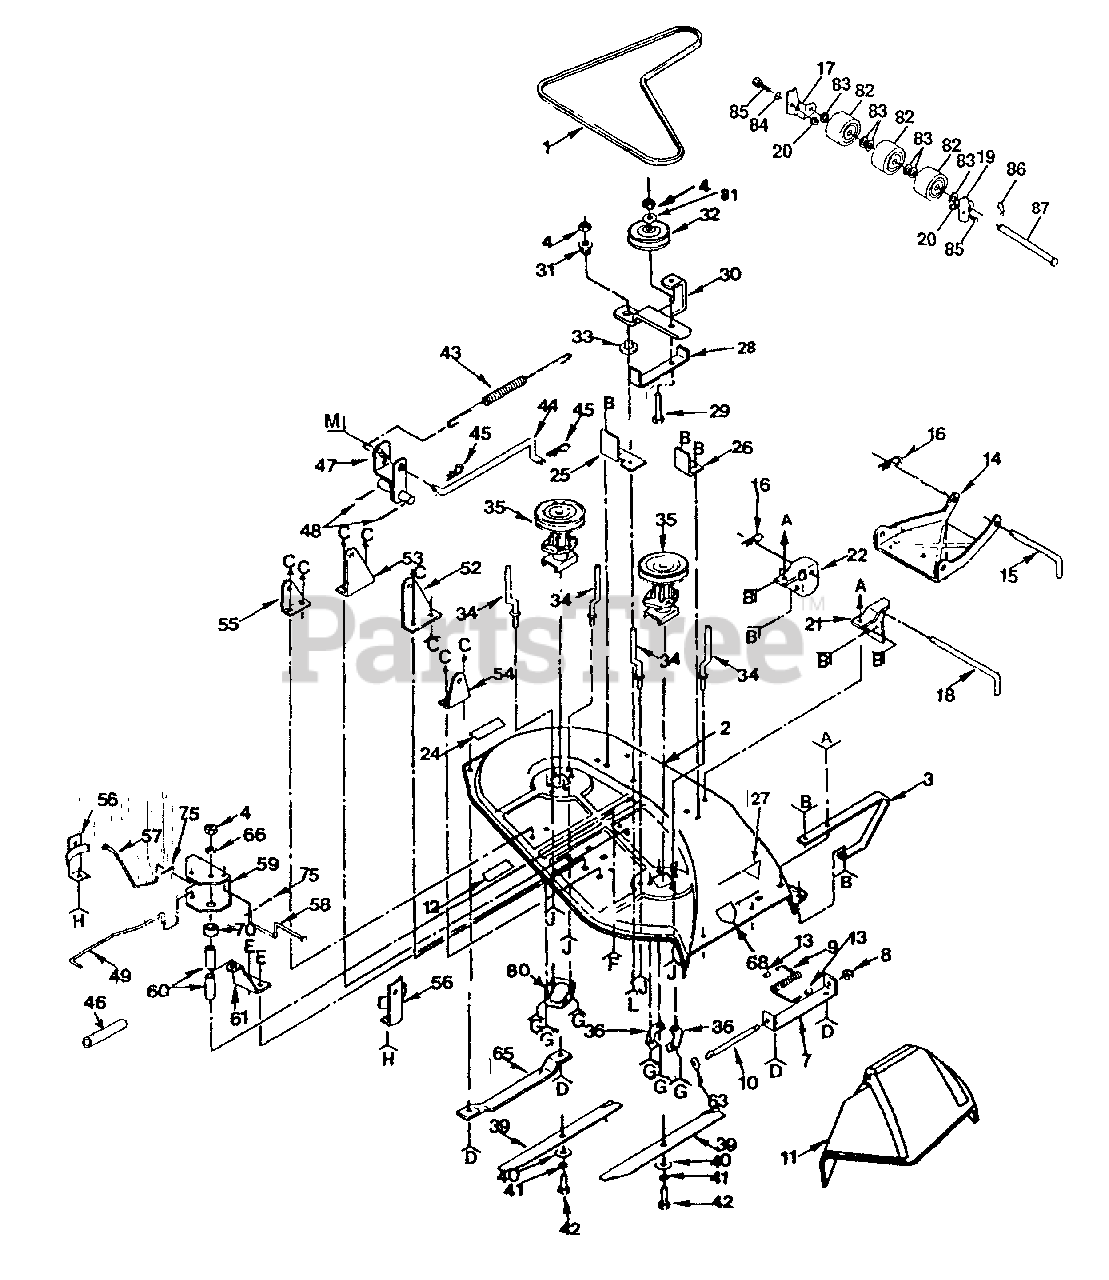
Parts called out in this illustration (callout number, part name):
2	Housing
3	Runner R.H.
4	Nut, Lock 3/8 - 16
7	Bracket, Deflector
9	Spring, Deflector
10	Rod, Hinge
11	Deflector, Shield
12	Decal, V-Belt Mower Drive
14	Link, Parallel
15	Pin, Hinge, Front
16	Spring, Retainer
17	Bracket, Nose Roller L.H.
18	Pin, Hinge, Rear
19	Bracket, Nose Roller R.H.
20	Nut, Lock 5/16 - 18
21	Bracket, Lift R.H.
22	Bracket, Lift L.H.
24	Decal, Instruction, Caution
25	Support, Arm
26	Stop, Deck, Front
27	Decal, Safety Standard
28	Guide, Belt
29	Bolt 3/8 - 16 x 2
30	Arm, Idler Assembly
32	Pulley, Idler
33	Washer, Wear 1/16
34	Keeper, Belt
35	Mandrel, Assembly
36	Plate, Support, Mandrel
39	Blade
40	Washer 13/32 x 1 - 1/4 x 12 Ga.
41	Washer, Lock 3/8
42	Bolt, Hex 3/8 - 24 x 1 -1/2 Gr. 5
43	Spring, Ext.
44	Rod, Clutch, Mower
45	Spring, Retainer
47	Rock Shaft Assembly
48	Pin, Cotter 3/16 x 1
49	Rod, Brake, Primary
52	Bracket, Pivot R.H.
53	Bracket, Pivot L.H.
54	Bracket, Susp., Rear R.H.
55	Bracket, Susp., Rear L.H.
56	Brake Assembly
57	Rod, Brake, Secondary L.H.
58	Rod, Brake, Secondary R H.
59	Bracket, Brake, Pivot
60	Spacer, Brake
61	Bracket, Support
63	Washer 11/32 x 5/8 x 16 Ga.
65	Runner L.H.
66	Washer 13/32 x 1 x 14 Ga.
68	Decal, Warning
75	Pin, Cotter 3/32 x 1/2
80	Plate, Support L.H.
81	Washer, 13/32 x 13/16 x 16 Ca.
82	Roller.Nose.
83	Washer 15/32 x 1 x 10
84	Washer 1/2 x 1 x 16 ga.
85	Bolt, hex 5/16-18 x 3/4
86	Pin, Cotter 1/8 x 3/4
87	Pin, Pivot.
